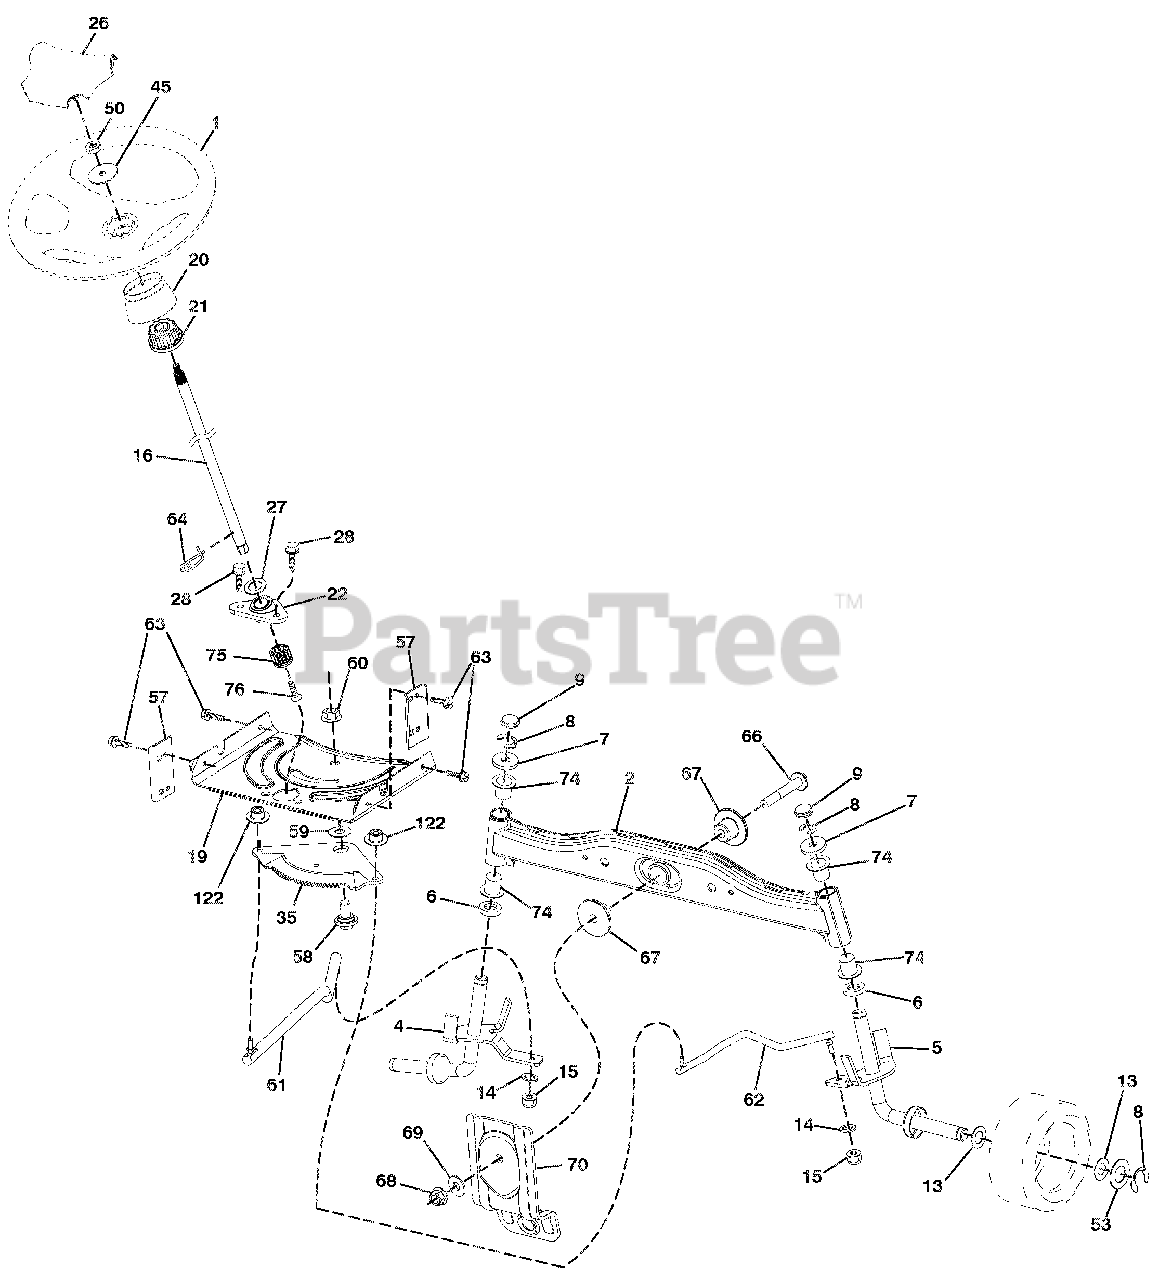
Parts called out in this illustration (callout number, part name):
1	WHEEL STEERING
2	AXLE ASM.WELDED
4	SPINDLE.WELDED.LH.15"TEX
5	SPINDLE.WELDED.RH.15"TEX
6	WAHSER THRUST .75 X 1.230
7	WASHER.25/32 X 1-5/8 X 16GA.
8	RING.KLIP.#T5304-75
9	CAP.SPINDLE.FR.TOP.BLK.
13	WASHER.25/32 X 1 1/4 X 16 GA.
14	Washer, Lock 3/8
15	NUT.CROWNLOCK.3/8-24
16	SHAFT STEER
19	PLATE.STEER.DDL.NLT/NGT
20	BOOT.STEERING
21	ADAPTER.STEER
22	STEER.SUPT. LOWER
26	CAP WHEEL STEERING HRS/SRS BLK
27	WASHER 21/32 X 1 X 1 GA.
28	SCREW.HEXWSH THDR3/8-16X3/4.BL
35	GEAR SECTOR.PLATE.DDL.NLT/NGT
50	Nut, Hex, Flangelock 3/8-16
53	WASHER.HARDEN..793 X 1.637X060
57	BRACKET.UPSTOP.TEX
58	BOLT.SHOULDER.SECTOR.PIVOT.CFM
59	WASHER.THRUST.SECTOR.STEER.NLT
60	NUT.FLANGE LOCK.5/8-11
61	DRAGLINK.LH.BALLSTUD.DDL.
62	DRAGLINK.RH.BALLSTUD.DDL
63	SCREW.5/16-18X3/4.SMGML.TAP/BL
64	RETAINER.CLIP.SPRING.STEERING
66	BOLT.HEX.FGHD.7/16-14 X 3.SERR
67	BUSHING.PM.FRONT AXLE
68	NUT.LOCK.FLANGE.7/16-14.GR5
69	WASHER.1.5 X .505 X .118
70	BRACKET
74	BEARING COL STRNG BLK
75	PINION
122	CAP GEAR SECTOR
